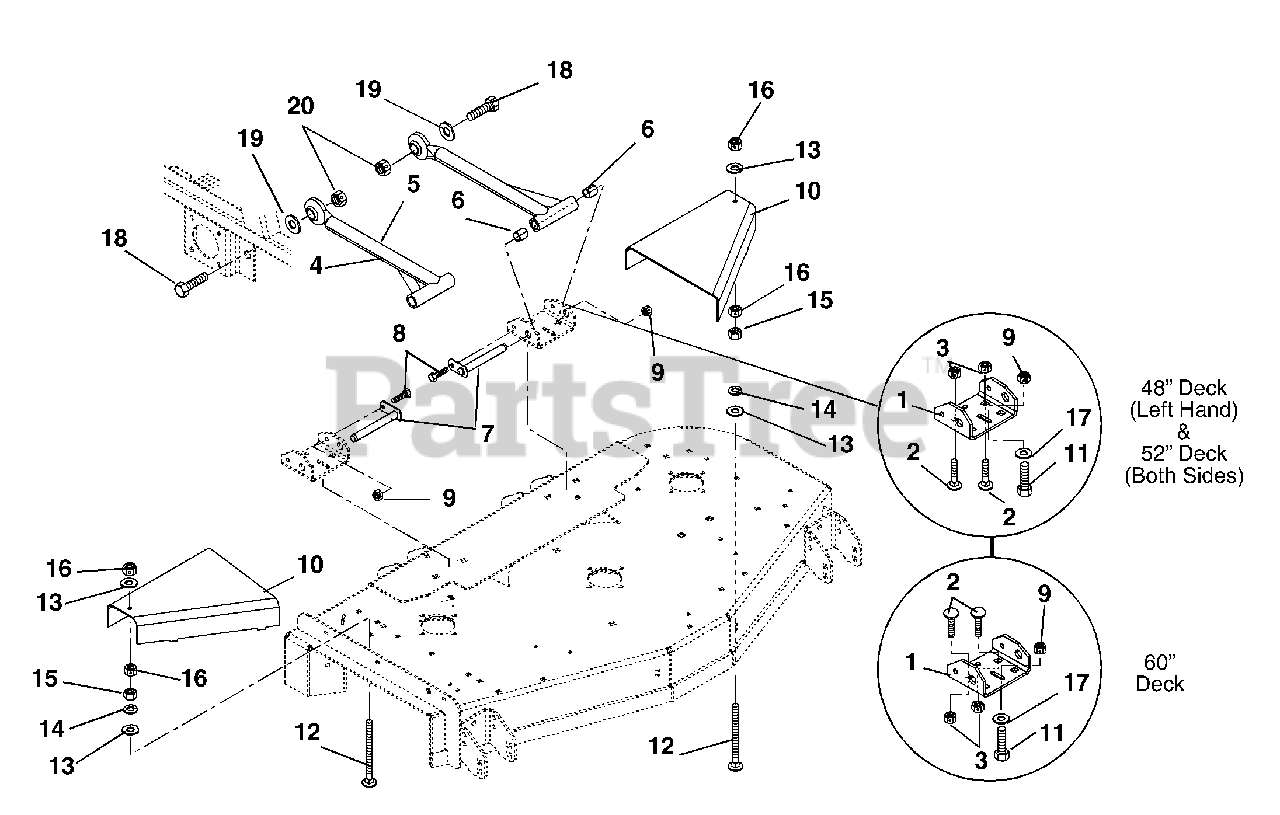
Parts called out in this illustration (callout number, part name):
1	BRKT, MOWER MOUNT - ORANGE
2	@BLT-RDHDSQNK .50-13X.75 G5YZ
3	NUT-LK-CTR-JAM .50-13 YWZC(ND)
4	ASSY, MOWER MOUNTING
5	MOWER MTG ARM - BLACK
6	BRG, .750 X .875 X 1.000
7	WELDMENT, MOWER MTG. PIN
8	@BLT-HEX .38-16X.75 GR5 YWZC
9	@NUT-LK-TOP-FLG .38-16 YWZC
10	GUARD, PULLEY LH - ORANGE
10	GUARD, PULLEY RH - ORANGE
11	@BLT-RDHDSQNK .38-16X.75 G5YZ
12	BLT-RDHDSQNKFTH.312-18X3.50YWZ
13	@WSHR-FL-STL.344X.688X.065YWZC
14	@WSHR-LK .31X.078 REG YWZC
15	@NUT-HEX .31-18 YWZC
16	@NUT-LK-CTR .31-18 YWZC
17	@WSHR-FL-STL.406X.812X.065 YWZ
18	BLT-HEX .875-9X2.75 GR5 YWZC
19	WSHR-FL-STL .890X1.500X.1196YZ
20	NUT-LK-CTR .875-9 YWZC
